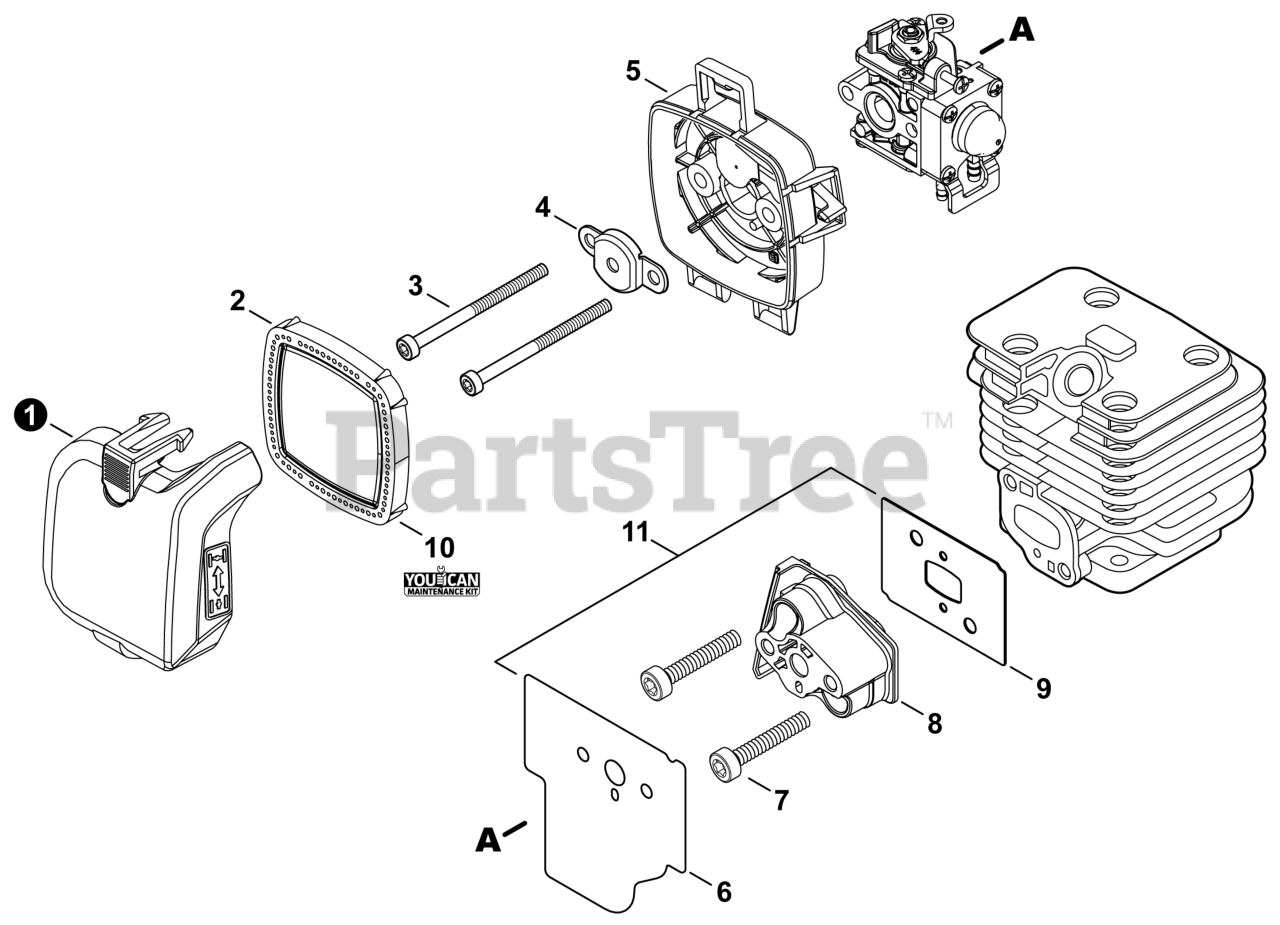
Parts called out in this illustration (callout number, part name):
1	COVER, AIR FILTER
2	FILTER, AIR
3	BOLT, TORX 5x65
4	PLATE, PREVENT
5	CASE, AIR FILTER
6	GASKET, INTAKE
7	BOLT, TORX 5x20
8	INSULATOR, INTAKE
9	GASKET, INTAKE
10	TUNE-UP KIT - YOUCANT
11	GASKET KIT
